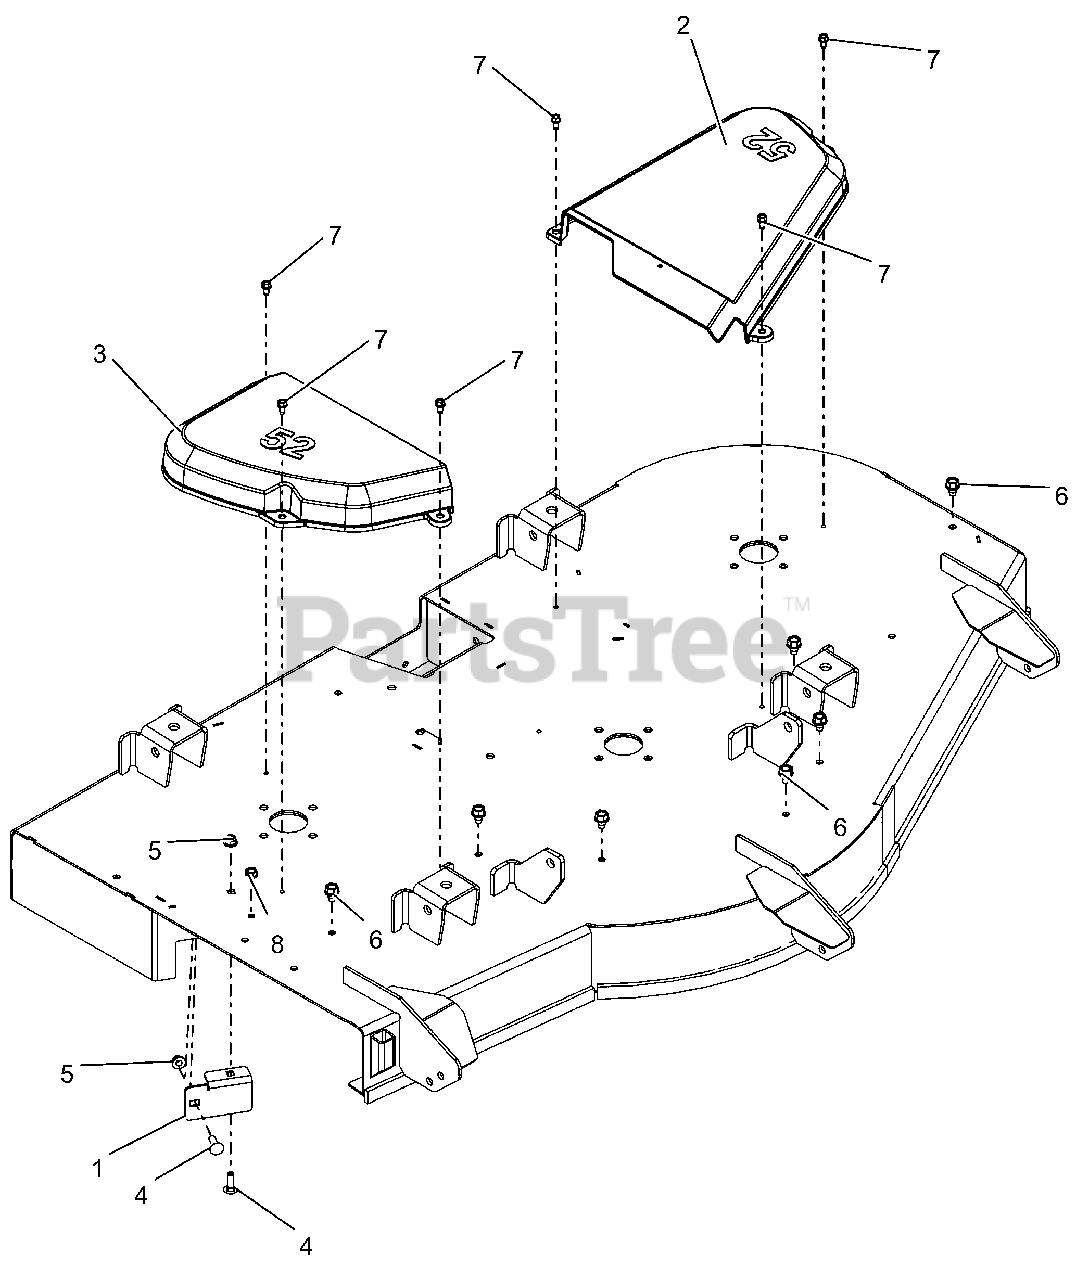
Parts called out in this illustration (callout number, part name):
1	STRIP, DEFLECTOR - 52"
2	COVER, BELT 52" LH
3	COVER, BELT 52" RIGHT
4	BLT,RHSN .31-18X1.00 G5 ZCC
5	NUT,NYL-FLG .31-18 GF ZCC
6	SCR,TAP .375-16X.50 HWH TR ZCC
7	SCR-TAP .25-20X.50 HWH ZCC
8	SCR,TAP .312-18X.50 HWH TR ZCC
